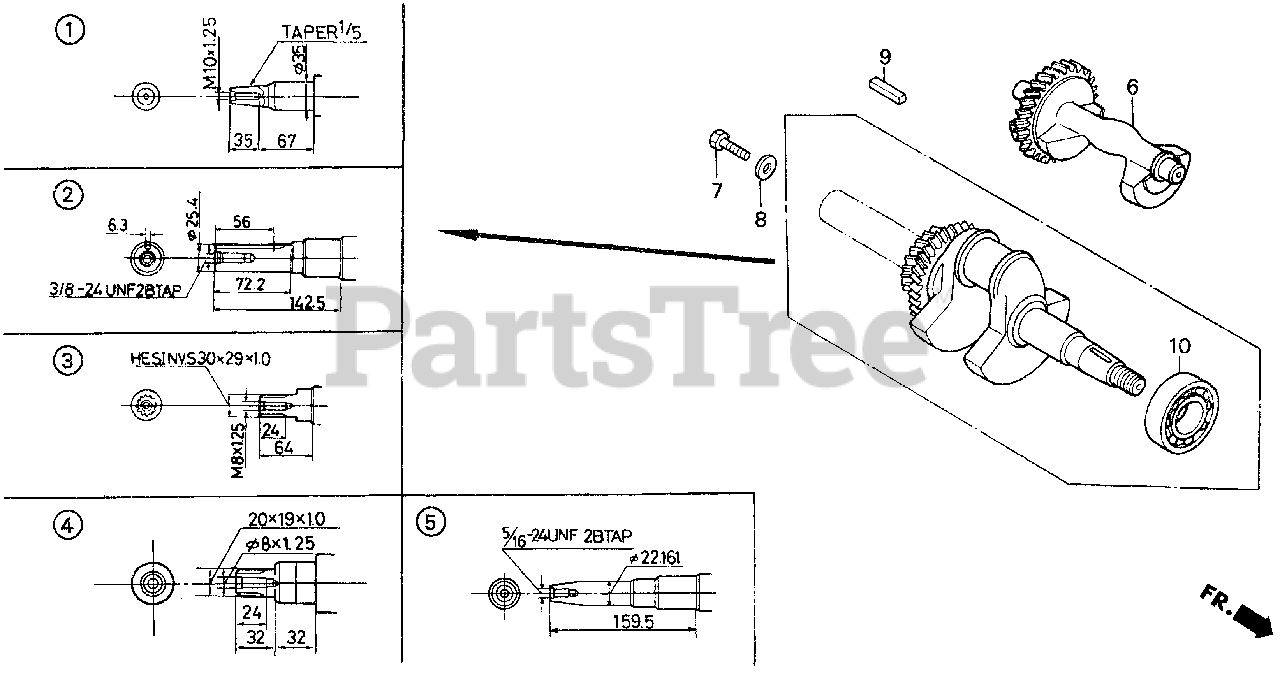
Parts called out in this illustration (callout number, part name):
2	CRANKSHAFT (Q-TYPE)
6	WEIGHT, BALANCER
9	KEY (6.3X6.3X43)
10	BEARING, RADIAL BALL (6207S)
